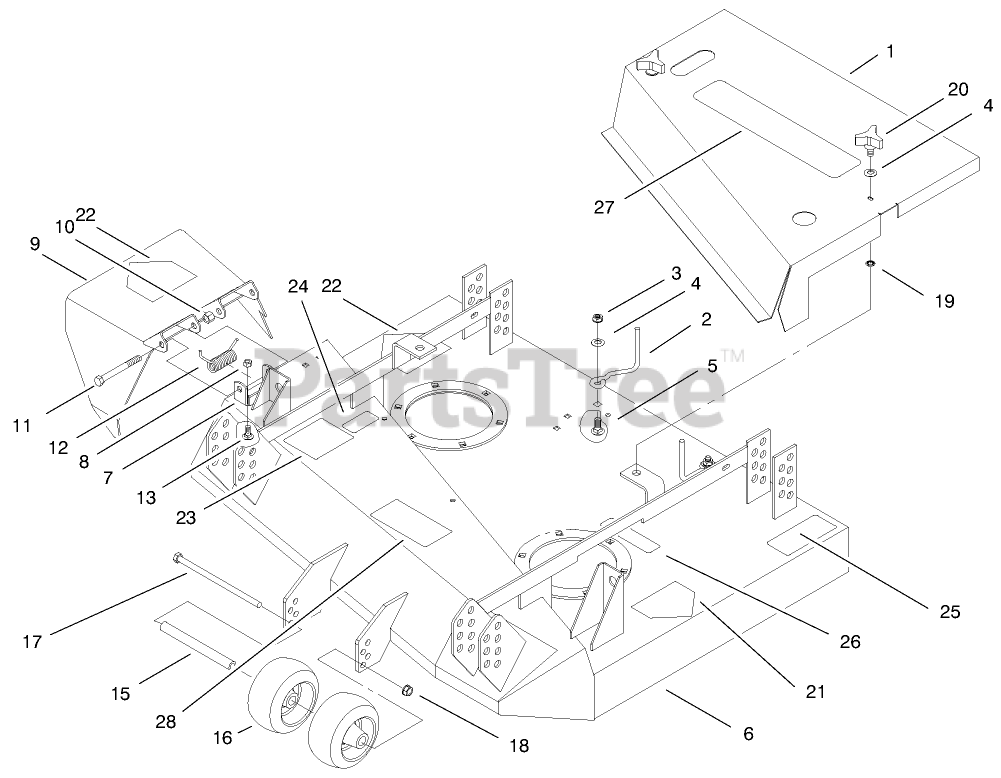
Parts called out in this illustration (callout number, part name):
1	Cover ASM
2	ROD-BELT
3	NUT-HF
4	WASHER-FLAT
5	SCREW-CARR
6	Deck ASM
7	BRACKET-PIVOT
8	NUT-LOCK, CONE
9	Deflector-Grass
10	NUT-HEX
11	SCREW-HH
12	SPRING
13	SCREW-CARR
15	SPACER-WHEEL
16	WHEEL-GAGE
17	SCREW-HH
18	NUT-LOCK, NI
19	RING-RETAINING
21	DECAL-DANGER
22	DECAL-DANGER
23	DECAL
25	DECAL-TORQUE
26	DECAL-DANGER
27	DECAL-36"
28	DECAL-DANGER, THROWN OBJECT
